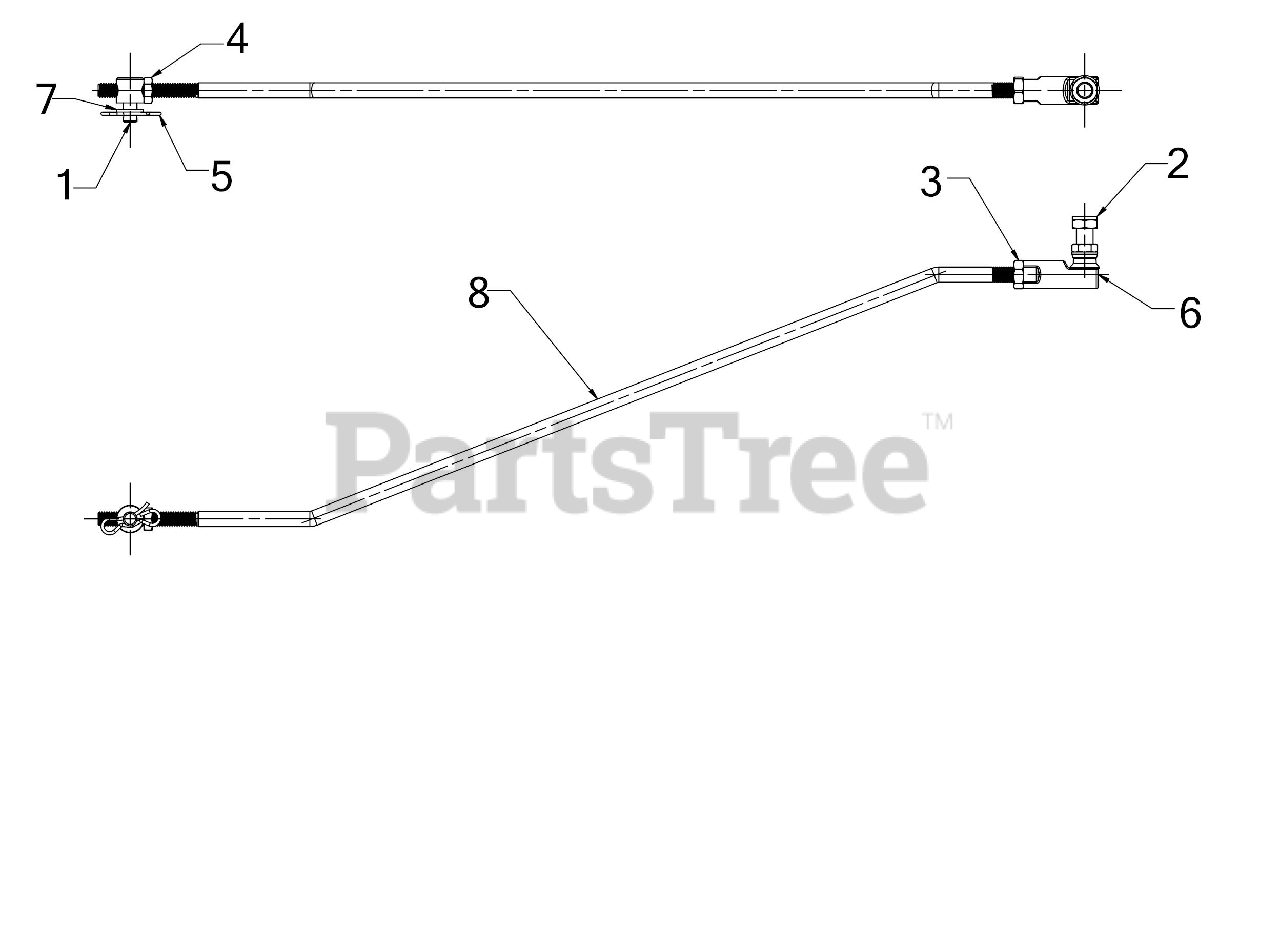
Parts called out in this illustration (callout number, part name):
1	FERRULE 5/16-18 x .312
2	HEX NUT
3	HEX JAM NUT 3/8X24
5	BOW TIE COTTER PIN 1/4-5/16
6	BALL JOINT
7	FLAT WASHER ID-.320 x .598
